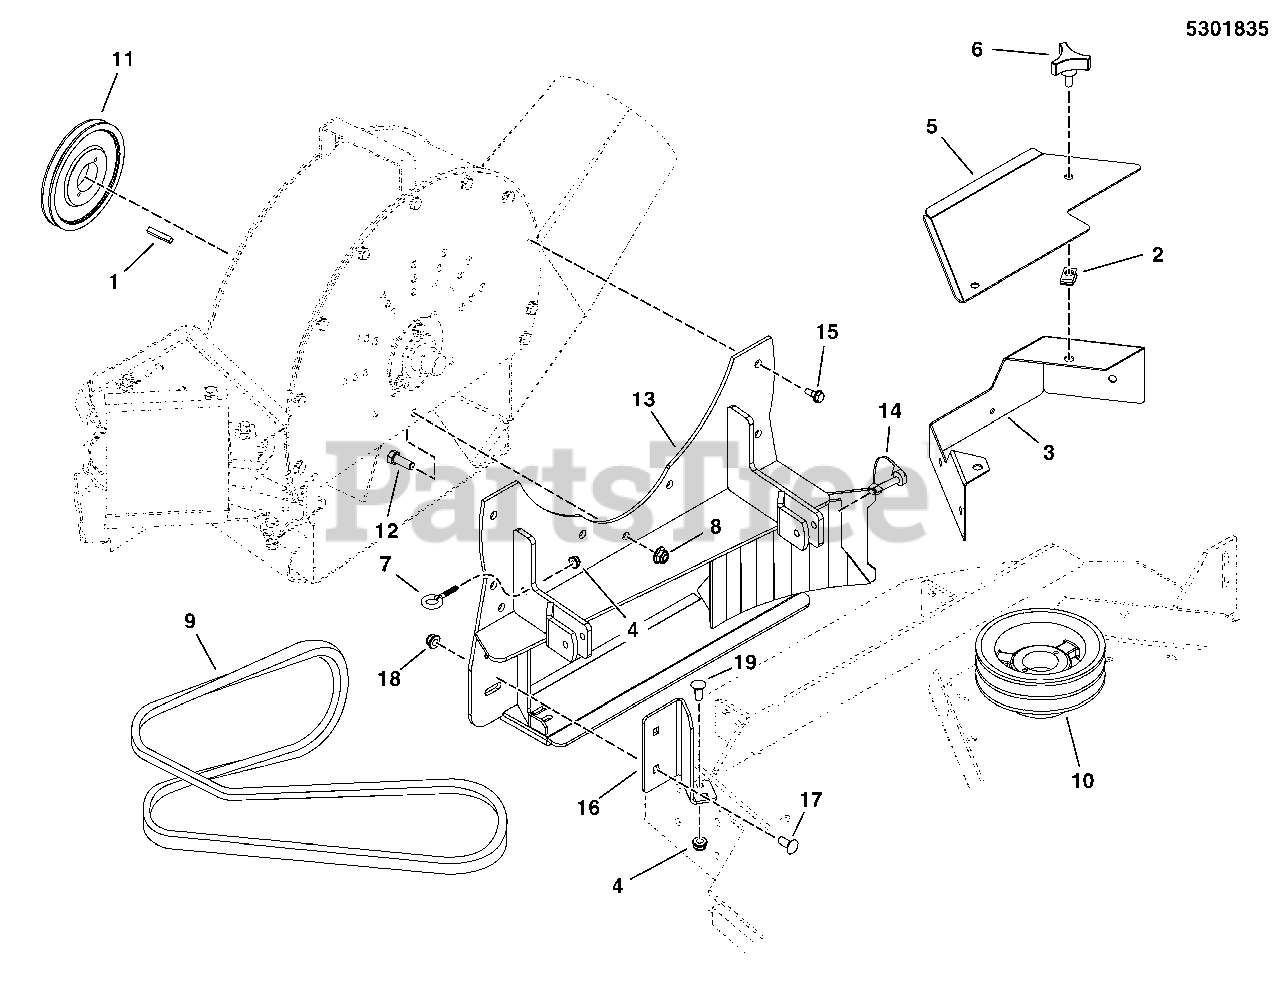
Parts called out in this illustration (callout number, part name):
1	KEY 1/4 SQ X 1 1/2 LONG
2	BODY CLIP, 5/16-18-7GA MATERIAL
3	GUARD, DECK, 61", 2000 FASTVAC - BLK
4	NUT, 1/4-20 HEX NYLOCK FLANGE (5025391)
5	GUARD, BELT, 61", 2000 FASTVAC - BLK
6	KNOB, PLASTIC, 5/16-18 X 3/4
7	EYEBOLT, 1/4-20 X 2
8	NUT, 3/8-16 HEX NYLOCK FLANGE
9	BELT, A-SEC, 92.00EL, ARAMID, WRPD
10	PULLEY,DECK,61 BLOWER UNIT
11	PULLEY, BLOWER AXLE, 61
12	BOLT, 3/8-16 X 1 GD5 YZ
13	WELD, BLOWER MOUNT, 61 - BLK
14	SNAPPERPIN, 5/16 X 2
15	BOLT, 5/16-18 X 5/8" Self Lock
16	BRACKET,DEFLECTOR PLATE, 61
17	BOLT, 5/16-18 X 3/4, CARRIAGE
18	NUT, 5/16-18 HEX NYLOCK FLANGE
19	BOLT-RD HD SH SQ NK 1/4-20X0. 625 G5 BLK
